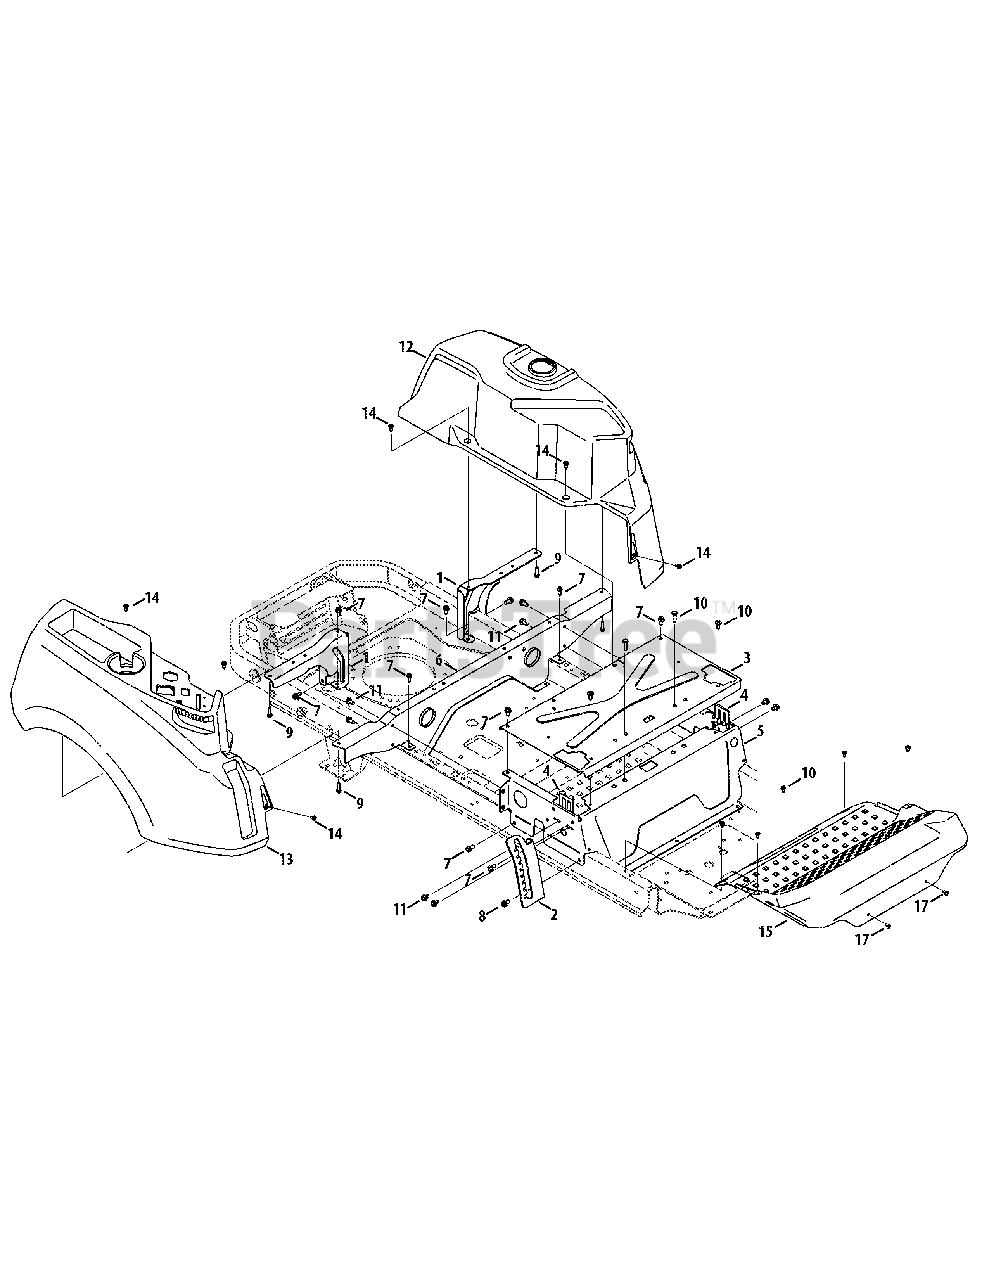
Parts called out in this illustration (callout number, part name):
1	Rear Tank Bracket
2	Height Index Bracket
3	Lap Bar Bracket Brace
4	Rear Seatbox Brace
5	Hex Washer Screw, 5/16-18 x .750
6	Hex Washer Screw, 5/16-18 x .750
7	Hex Washer Screw, 3/8-16 x 1.000
8	Hex Washer Screw, 5/16-14 x 1.00
9	Screw, 5/16-18 x .750
10	Hex Washer Screw, 5/16-18 x .500
11	Hex Washer Screw, 5/16-18 x .500
12	LH Console
13	RH Console
14	Shoulder Screw, 1/4-20
15	Floor Board
16	Screw, 1/4-20 x .5
17	Screw, 5/16-18 x .750
